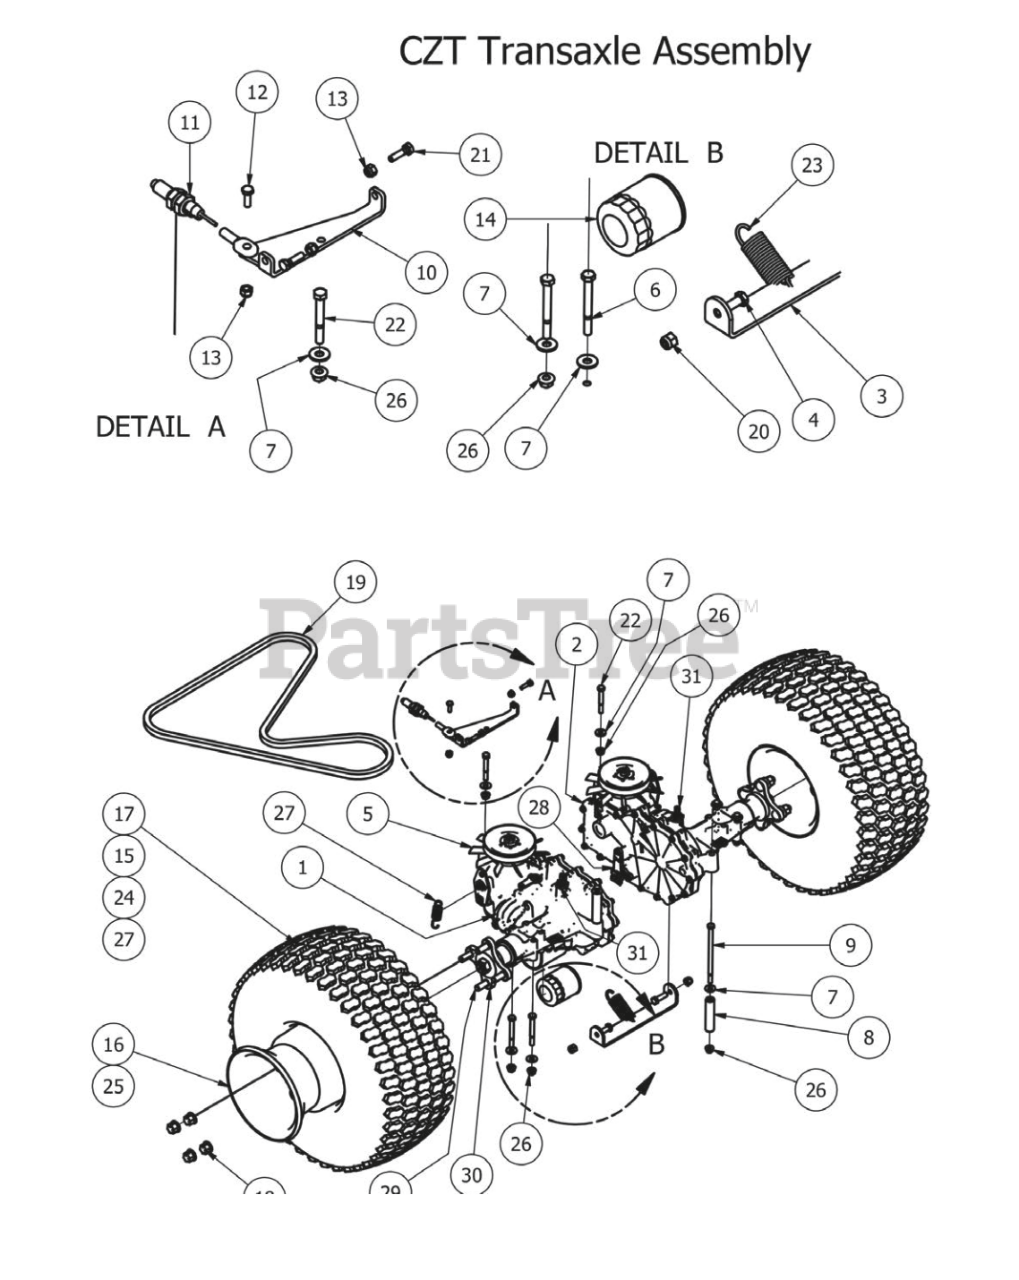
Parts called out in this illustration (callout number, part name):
1	3400 IZT for CZT -Left
2	3400 IZT for CZT - Right
3	Crossover Bar for ZT
4	3/8" x2" Hex Bolt
5	Fan/Pulley kit For CZT
6	5/16" x 3" Hex Bolt
7	5/16" Flat Washer
8	3 1/4" Spacer
9	5/16" x 6" Bolt
10	ZT Crossover Brake Bracket
11	Brake Cable-Stand on
12	1/4" x 3/4" Hex Bolt
13	1/4" Nylock Nut
14	Transaxle Hydro Filter
15	Tire 23 X 10.50 -12 Assembly W/Negative Offset Wheel (54"& 60"Only Deck)
16	12 Orange Wheel (54" & 60")
17	23 x 10.50 Tire only
18	Acorn Lug Nut
20	3/8 Nylock Nut
21	1/4-20 x 1 GR 5 hex bolt zinc
22	5/16" x 2 1/2" Bolt
24	23x 10.5-12 Tire & Wheel Assembly (48" Only) Deck
25	12 Orange Wheel (Wheel Only 48" Deck)
26	5/16" Nylon Flange Nut
27	Transaxle Spring
28	Transaxle Brake Lever
29	Transaxle Wheel Studs
30	ZT Transaxle Hub
31	45 degree fitting
